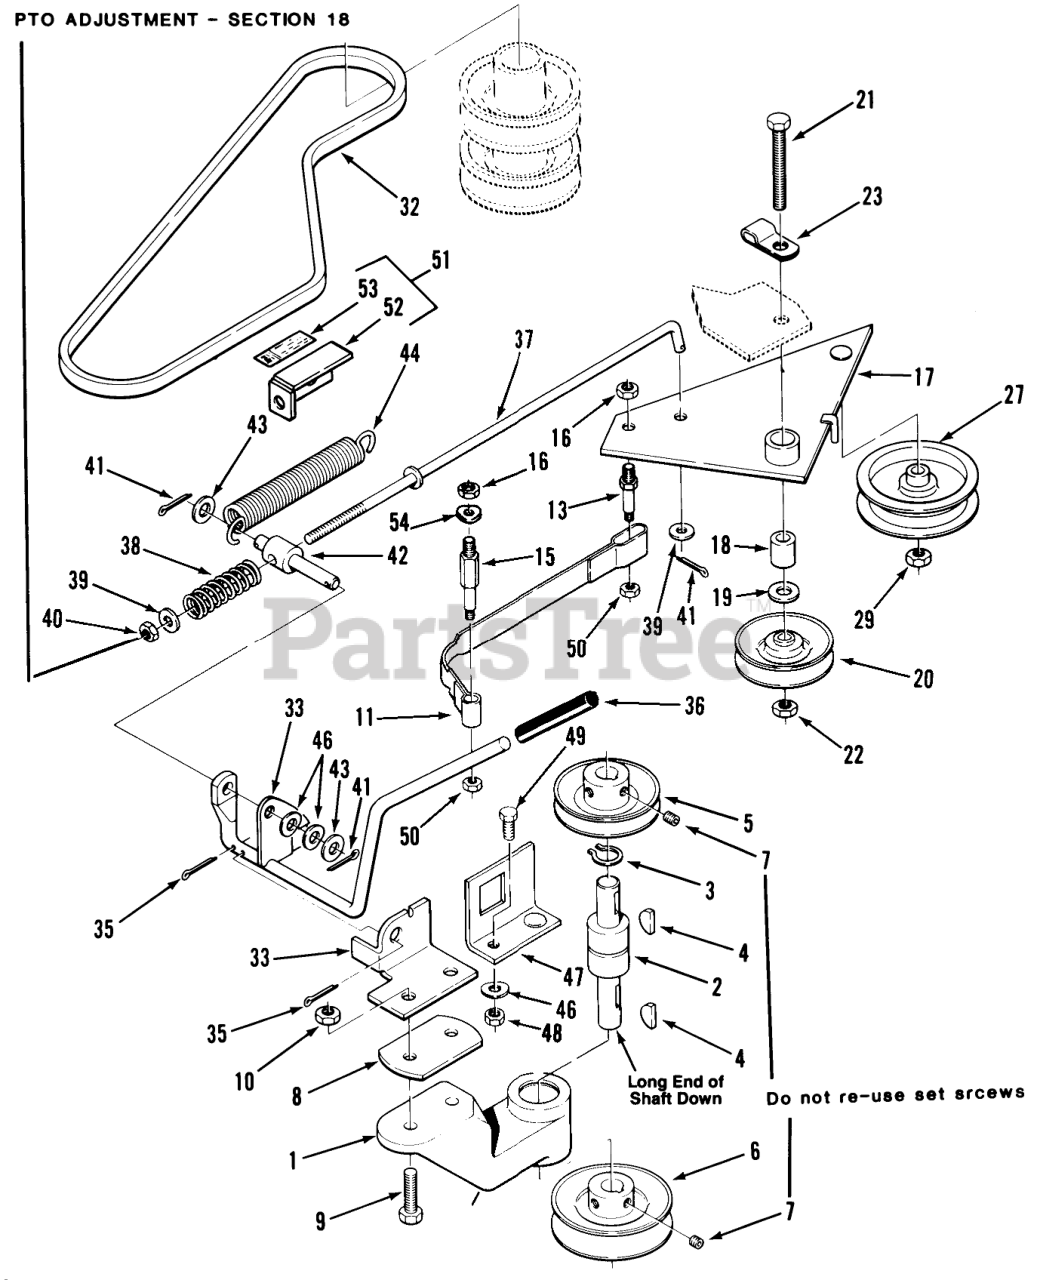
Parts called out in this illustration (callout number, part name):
1	Jack Shaft Housing
2	BEARING-INT SHAFT
3	Snap Ring
4	KEY-WOODRUFF
5	PULLEY UPPER
6	PULLEY
7	Set Screw
8	PLATE SPACER R
9	Bolt
10	NUT
11	BRAKE BAND
13	STUD-SHOULDER
15	STUD-SHOULDER LONG
16	Nut
17	ASSY LEVER BLADE R
18	SPACER
19	Washer
20	IDLER PULLEY R
21	Bolt
22	NUT
23	CLAMP DOUBLE
27	Flat Idler
29	NUT-HEX, JAM
32	V-BELT
33	ASSY HANDLE PTO CLUT
35	Cotter Pin
36	GRIP
37	ASSY ROD PTO
38	SPRING COMPRESSION
39	WASHER 5/16 SAE
40	Nut
41	Cotter Pin
42	TRUNNION
43	Washer
44	SPRING R
46	WASHER-SPRING
47	ASSY BRACKET SWIT R
48	Nut
49	H H C S
50	Nut
51	PTO Indicator Bracket Assy (includes items 52 & 53)
52	PTO INDICATOR BRC R
53	DECAL PTO INDICATOR
54	WASHER
